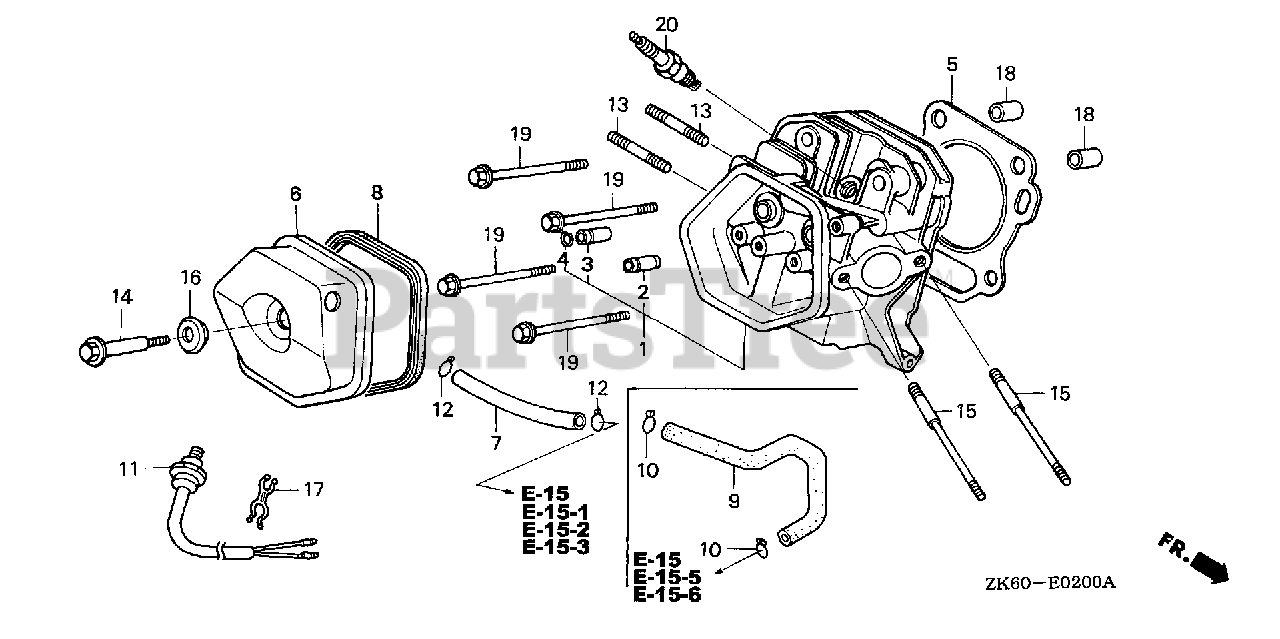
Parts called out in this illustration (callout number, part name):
1	CYLINDER HEAD
2	GUIDE, VALVE (OVER SIZE)
3	GUIDE, EX. VALVE (OVER SIZE)
4	CLIP, VALVE GUIDE
5	GASKET, CYLINDER HEAD
6	COVER, HEAD
7	BULK HOSE, VACUUM (11X1000) (11X105)
8	GASKET, HEAD COVER
13	BOLT, STUD (8X32)
14	BOLT, HEAD COVER
15	BOLT, STUD (8X131.5)
16	WASHER, HEAD COVER
18	PIN, DOWEL (12X20)
19	BOLT, FLANGE (10X80)
20	SPARK PLUG (BPR5ES) (NGK)
20	SPARK PLUG (W16EPR-U) (DENSO)
20	SPARK PLUG (BPR6ES) (NGK)
20	SPARK PLUG (W20EPR-U) (DENSO)
